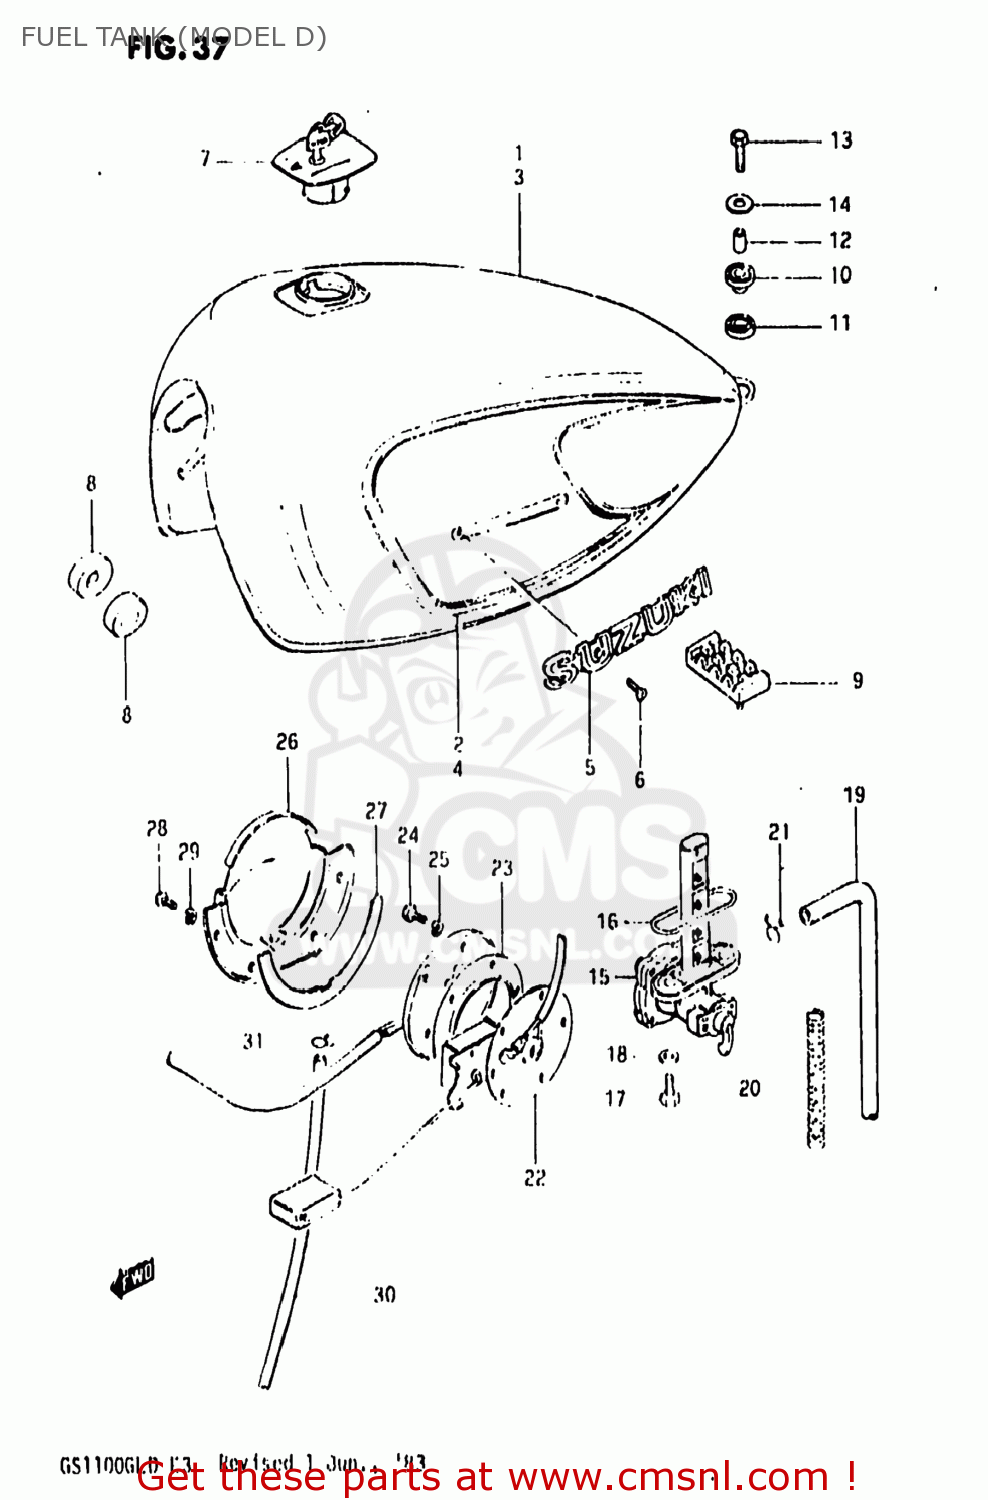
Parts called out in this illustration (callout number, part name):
1	TANK ASSEMBLY,FUEL
2	TAPE SET,FUEL TANK
3	TANK ASSEMBLY,FUEL
4	TAPE SET,FUEL TANK
5	EMBLEM,FUEL TANK
6	SCREW 3X6
7	CAP SET,FUEL TANK
8	CUSHION
9	CUSHION,FUEL TANK CTR
10	CUSHION
11	CUSHION
12	SPACER
13	BOLT
14	WASHER (6.5X24X1.6)
15	COCK ASSEMBLY,FUEL
16	O RING
17	BOLT(6X20)
18	GASKET
19	HOSE
20	SPRING
21	CLIP
22	GAUGE ASSEMBLY,FUEL LEVEL
23	GASKET,FUEL LEVEL GAUGE (NAS)
24	BOLT
25	LOCK WASHER
26	PLATE,FUEL DRAIN
27	GASKET (NAS)
28	SCREW
29	LOCK WASHER
30	HOSE,FUEL
31	CLIP
